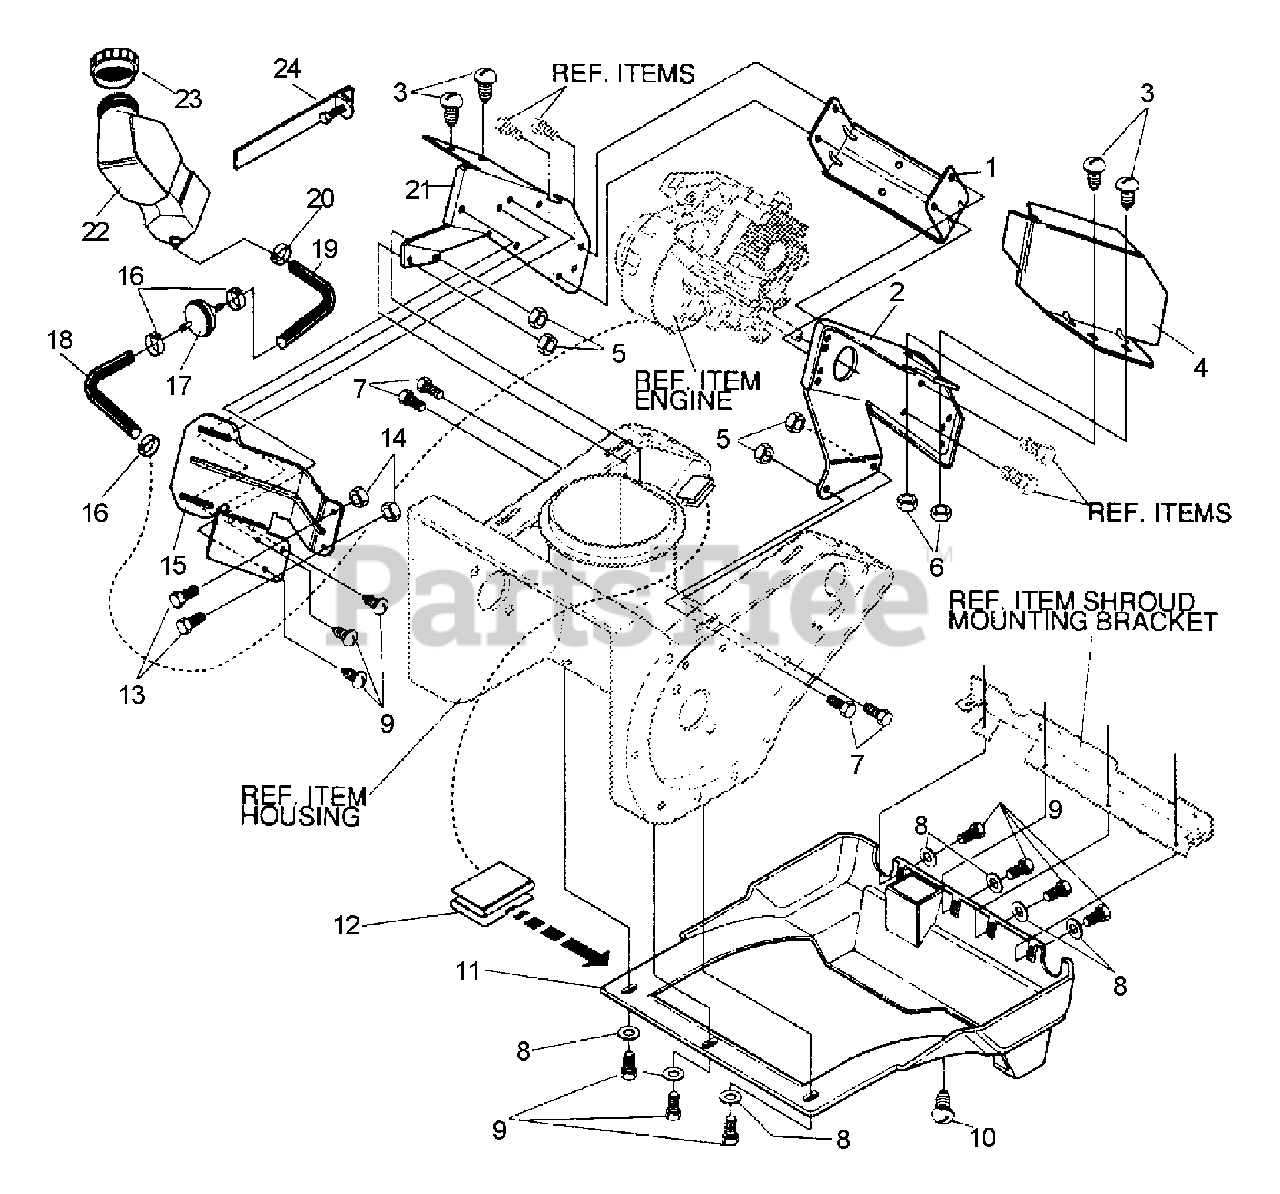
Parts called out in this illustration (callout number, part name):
1	SUPPORT, FRAME
2	PLATE, REAR MOUNT -- LEFT
3	SCREW - 1/4-20 X 5/8"
4	SHIELD, HEAT
5	NUT - 5/16-18
6	LOCKNUT - 1/4-20
7	SCREW - 5/16-18 X 1/2"
8	WASHER
9	SCREW - 10-24 X .63"
10	SCREW - 10-16 X .50"
11	SHROUD, BOTTOM
12	CLIP
13	SCREW - 10 X 24 X .50"
14	LOCKNUT - 10-24
15	BRACKET, FUEL TANK
16	CLAMP, HOSE
17	FILTER, FUEL
18	TUBING, GAS LINE 30"
19	TUBING, GAS LINE 8"
20	CLAMP, HOSE
21	PLATE, REAR MOUNT -- RIGHT
22	TANK, FUEL - 6.2 QUART
23	CAP, FUEL
24	CLAMP, WORM DRIVE
